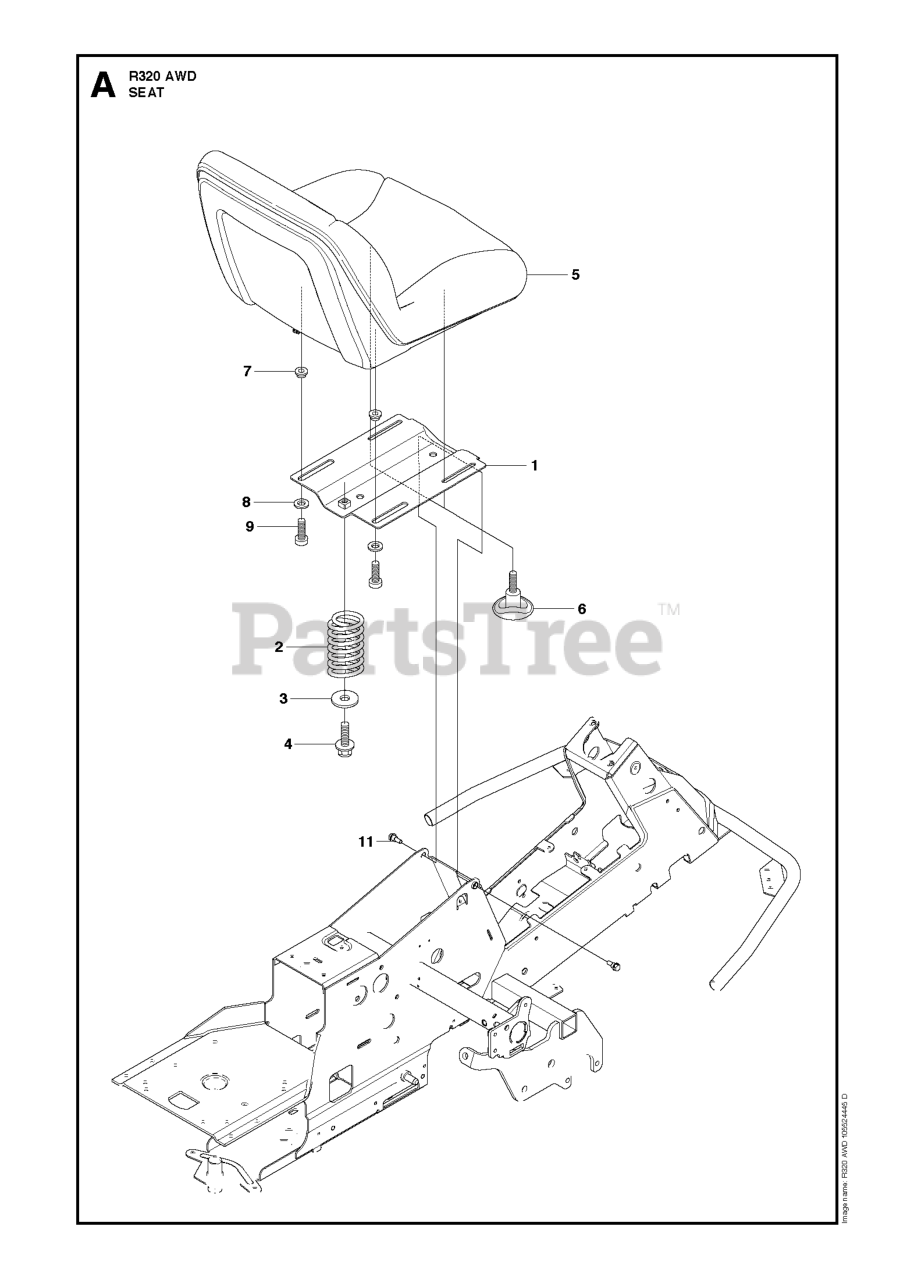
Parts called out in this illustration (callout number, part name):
1	SEAT BRACKET
2	SEAT SPRING
4	Screw M10x25
5	SEAT
6	ADJUSTING KNOB
